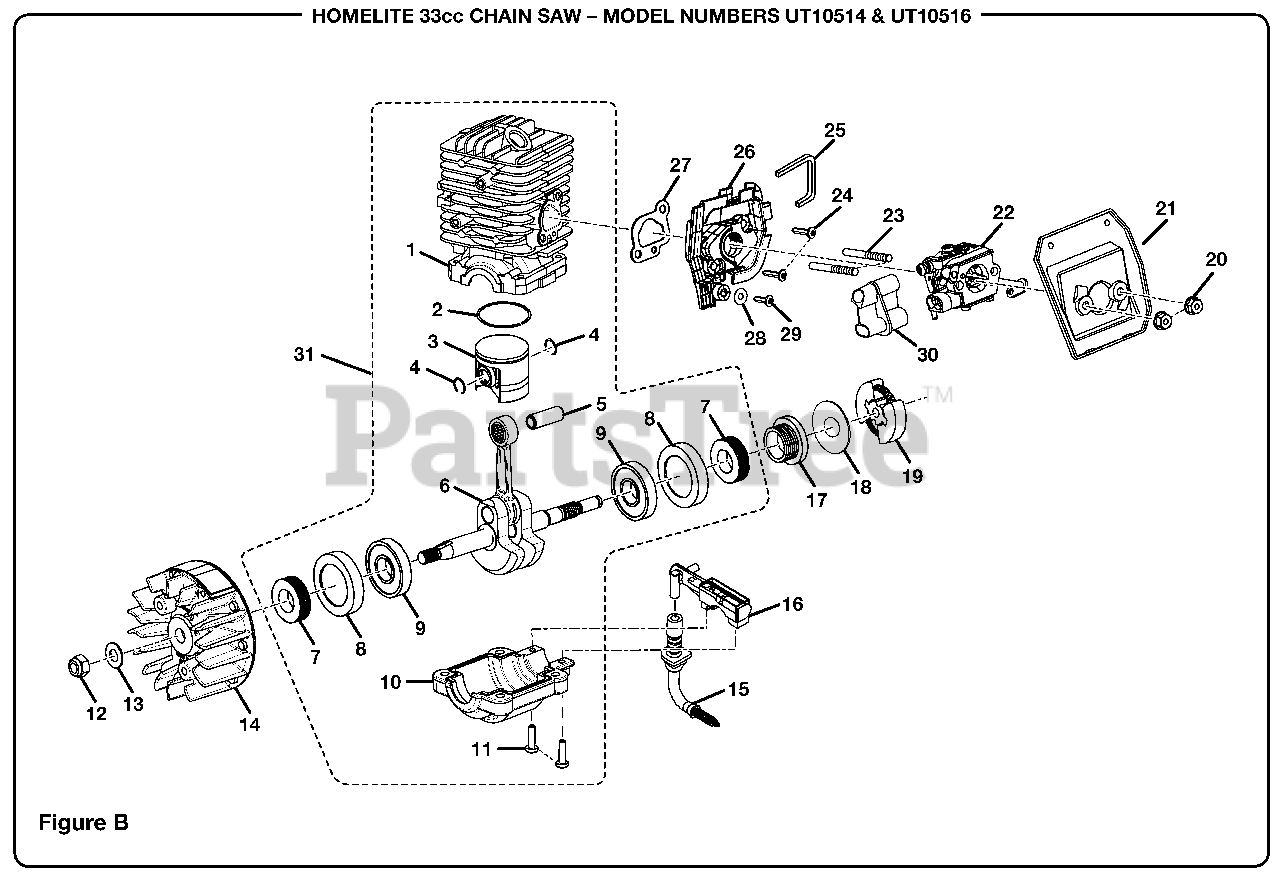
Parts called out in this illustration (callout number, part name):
2	Piston Ring
4	Retaining Ring
5	Piston Pin
6	Crankshaft Assembly
7	Shaft Seal
8	Bearing Case
9	Ball Bearing
10	Crankcase
11	Screw
12	Nut
13	Flat Washer
14	FlywheeL Assembly
15	Oil Intake Tube Assembly
16	Oil Pump Assembly
17	Left Hand Worm
18	Thrust Washer
19	Clutch Assembly
20	Flange Nut
21	Air Filter Plate
22	Carburetor Assembly
23	Screw
24	Screw
25	Spacer Seal
26	Carburetor Spacer
27	Heat Dam Gasket
28	Flat Washer
29	Screw
30	Carburetor Grommet
31	Short Block Assembly
